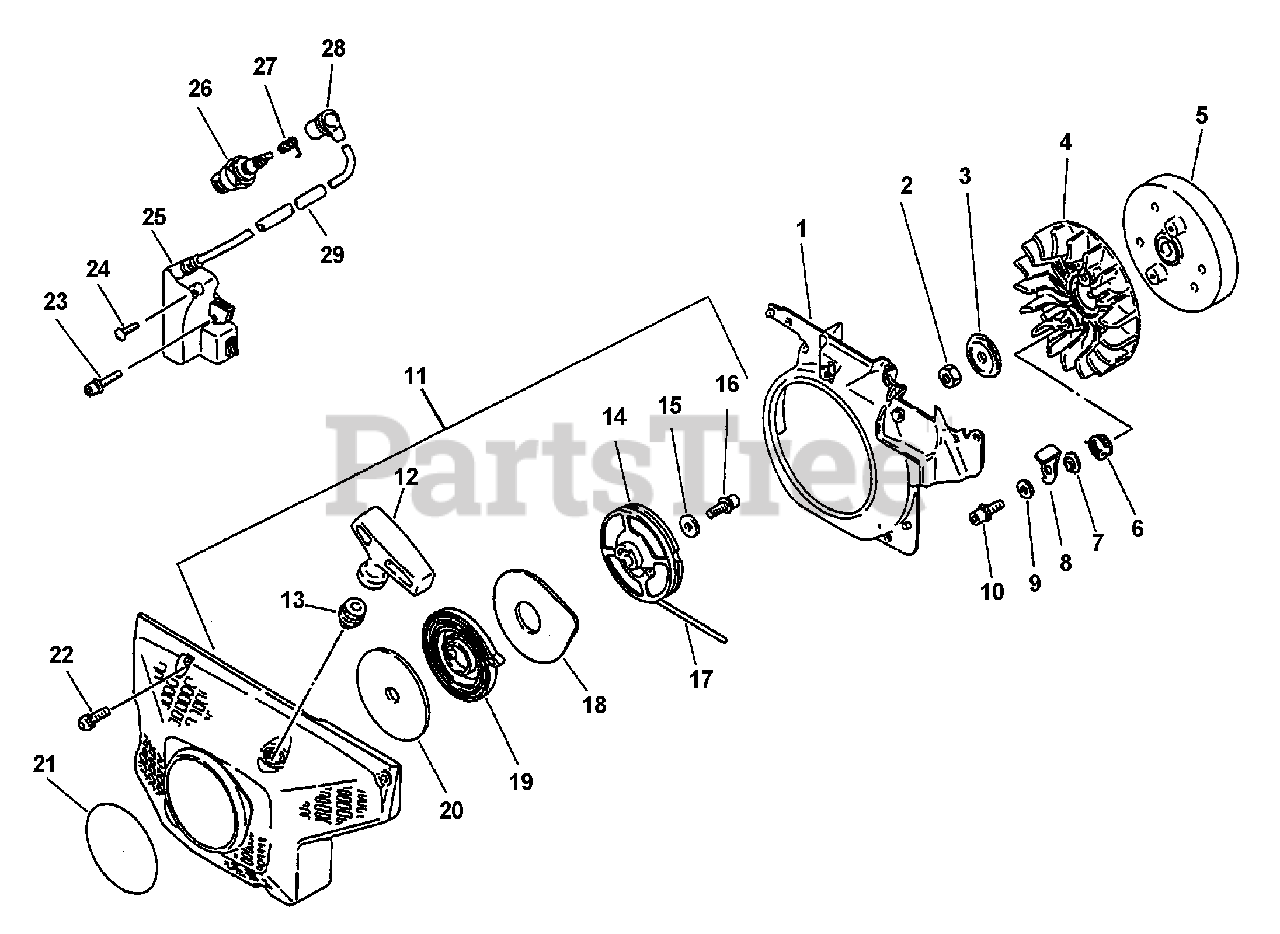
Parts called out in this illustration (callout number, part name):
1	SHIELD, FAN
3	WASHER 8.2×31×0.8
5	FLYWHEEL
6	SPRING, RETURN
8	PAWL, STARTER
9	WASHER 5.5×12×0.8
10	BOLT 5×14
11	STARTER ASSY
12	GRIP, STARTER
13	GUIDE, ROPE
14	REEL, ROPE
15	WASHER 5.5×12×0.8
16	BOLT 5×14
17	ROPE, STARTER
18	PLATE, STARTER
19	SPRING, RECOIL
20	PLATE, STARTER
21	LABEL - ECHO
22	BOLT 5×20
23	BOLT 4×20
24	SCREW 4×8
25	COIL, IGNITION
26	SPARK PLUG - BPM6A
27	TERMINAL, SPARK PLUG
28	CAP, SPARK PLUG
29	TUBE
